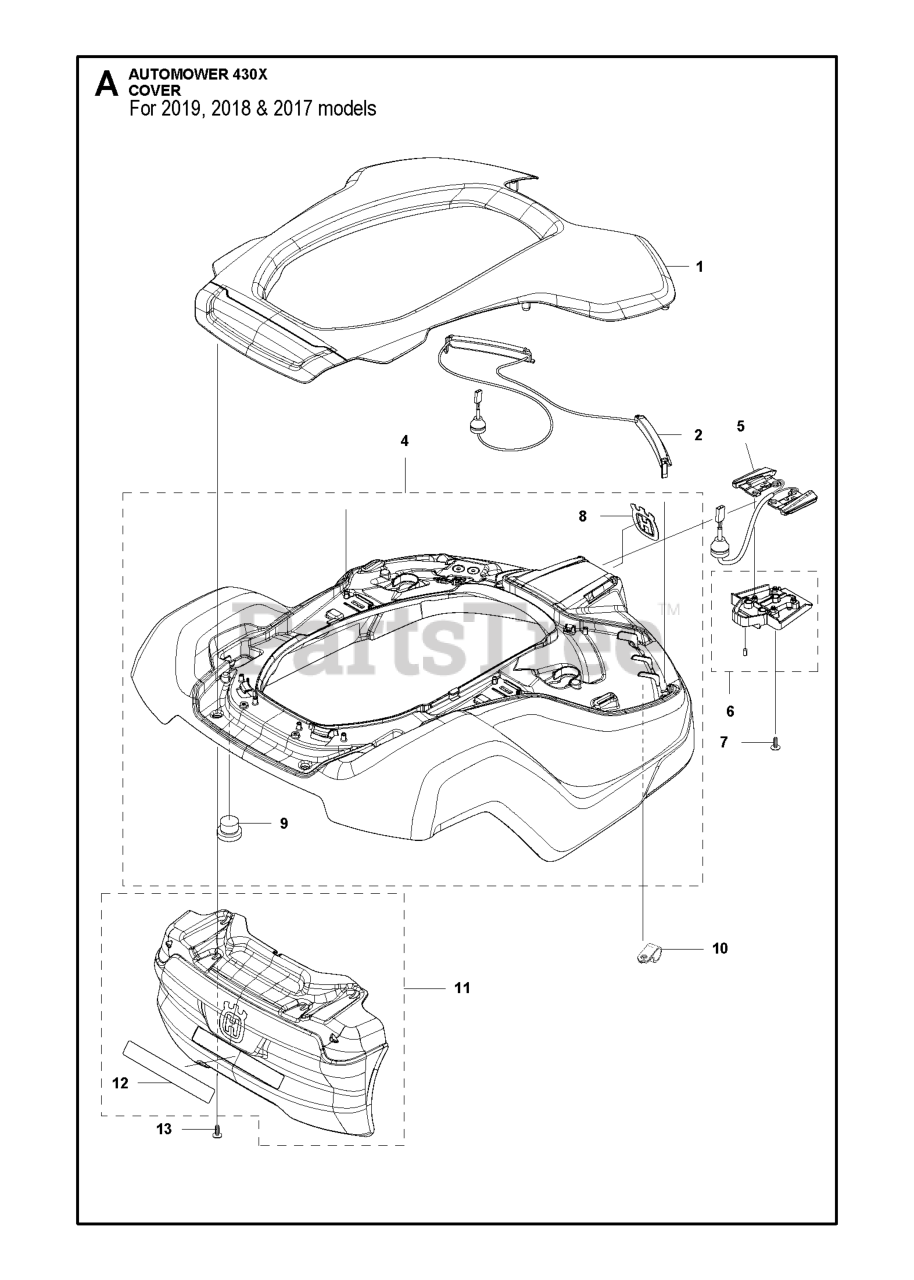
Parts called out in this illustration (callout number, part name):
1	BODY KIT GREY 430X 2018+
1	BODY KIT WHITE 430X 2018+
1	BODY KIT ORANGE 430X 2018+
2	WIRING ASSY LED
5	CABLE ASSY CHARGING PLATE
6	HOLDER ASSY MAGNET
7	SCREW 14MM
8	DECAL HUSQVARNA CROWN HEIGHT 5
9	CAP SNAPLOC
10	CLAMP P-CLIP
11	BUMPER ASSY
12	LABEL WARNING P15
13	SCREW ITXPANT
